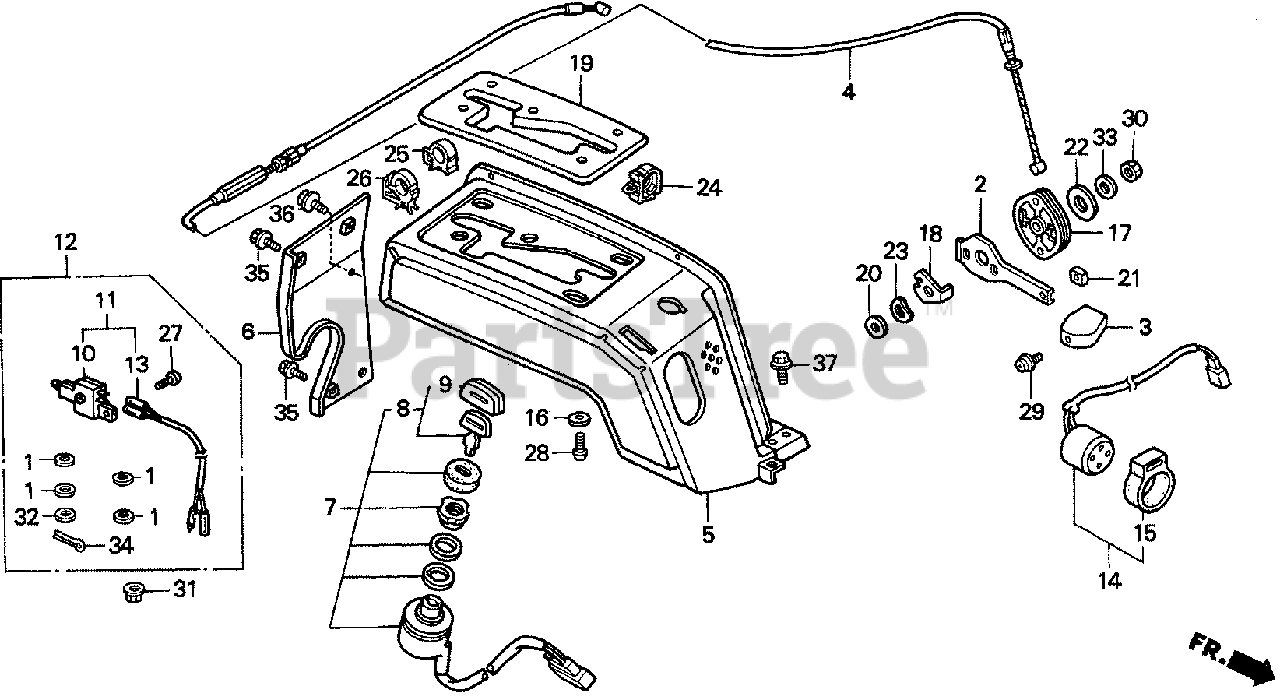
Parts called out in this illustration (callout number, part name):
1	WASHER, CONTROL (SOURCE: VINTAGE PARTS INC.)
2	LEVER, THROTTLE
3	KNOB, THROTTLE LEVER
4	CABLE, THROTTLE
5	GUIDE, CHANGE LEVER *R165* (JOLLY RED)
6	STAY, CHANGE GUIDE
7	SWITCH ASSY., COMBINATION
8	KEY ASSY., COMBINATION SWITCH
10	SWITCH ASSY., CLUTCH
11	SWITCH ASSY., NEUTRAL
12	SWITCH SET, NEUTRAL
13	WIRE, NEUTRAL SWITCH
14	BUZZER ASSY., WARNING
15	SUSPENSION, AUDIBLE PILOT
16	WASHER (5MM)
17	REEL, CONTROL CABLE
18	STOPPER, REEL
19	TRIM, CHANGE GUIDE *R165* (JOLLY RED)
20	WASHER (11MM)
21	NUT, SQUARE (4MM)
22	WASHER, THRUST (16.2X30X2.0)
23	WASHER, WAVE (12MM)
24	CLIP, WIRE HARNESS
25	CLIP, CABLE (8MM)
26	CLIP, CABLE (10MM)
27	SCREW, PAN (4X12)
28	SCREW, PAN (5X6)
29	SCREW-WASHER (4X8)
30	NUT, HEX. (6MM)
31	NUT, FLANGE (6MM)
32	WASHER, PLAIN (6MM)
33	WASHER, PLAIN (6MM)
34	PIN, SPLIT (2.0X12)
35	BOLT, FLANGE (6X12)
36	BOLT, FLANGE (6X16)
37	BOLT, FLANGE (8X16)
